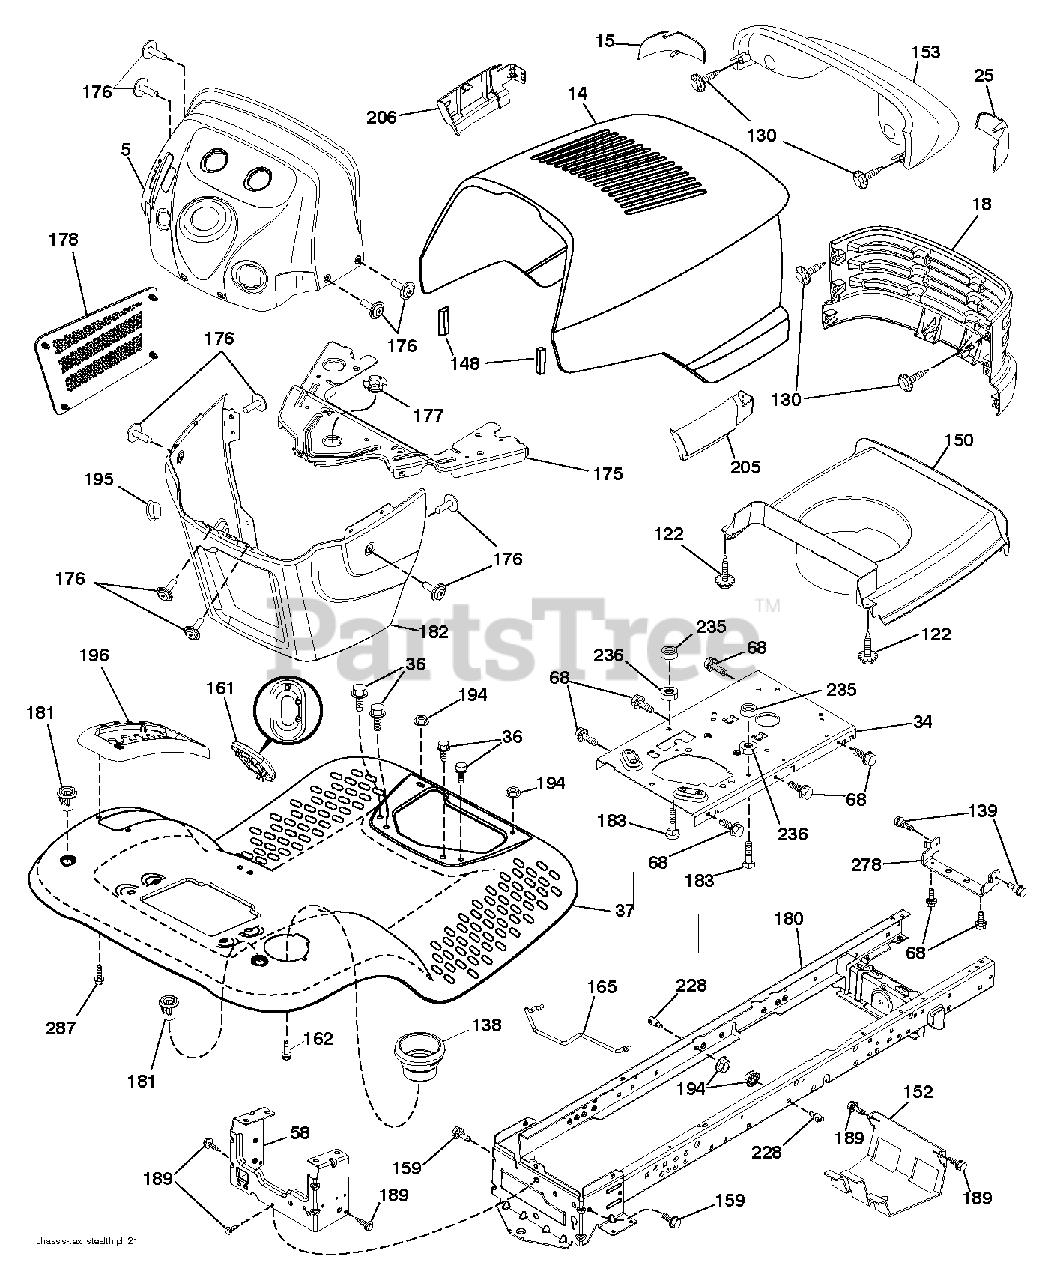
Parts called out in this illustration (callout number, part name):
5	DASH.UPR.STEALTH
15	LENS LH
25	LENS RH
37	FENDER.TLT.W/CPH.W/FW.666
58	DRAWBAR UPPER
68	SCREW LT
130	SCREW.#10 X 0.750.BOS THREAD
138	CUPHOLDER
148	EXTRUSION BUMPER
150	DUCT HEAT HOOD
152	SHIELD BROWNING
159	SCREW, 3/8-16X3/4
161	WINDOW.FUEL.LT.TEX.428
162	SCREW,HEX
165	SUPPORT.TANK.REAR.W/TE
175	CROSSMEMBER.
176	SCREW.#10-24X5/8.RN.QU
177	BUSHING.STEERING.YT/GT
178	CARGO.ASM.NET.DASH.LOWER
180	CHASS.WLDMNT.TL.12GA/2P.48/54
181	FEND/FTRST.PCH.CPH.NFW
182	DASH.LOWER.
183	BOLT.5/16-18X1-1/4 FULL THD
189	SCREW
194	NUT LOCK HEX FLANGE 5/16-18
195	PLUG.HOLE.DASH.LOWER.1
196	CONSOLE ASM. DECK LIFT
205	SKIRT.GRILLE.STEALTH.RH
206	SKIRT.GRILLE.STEALTH.LH
228	STUD.FASTNER.W/D.ANTI-
235	SPACER FENDER
236	JAM LOCK NUT
278	BRKT.HOOD/MUFF.STEALTH
